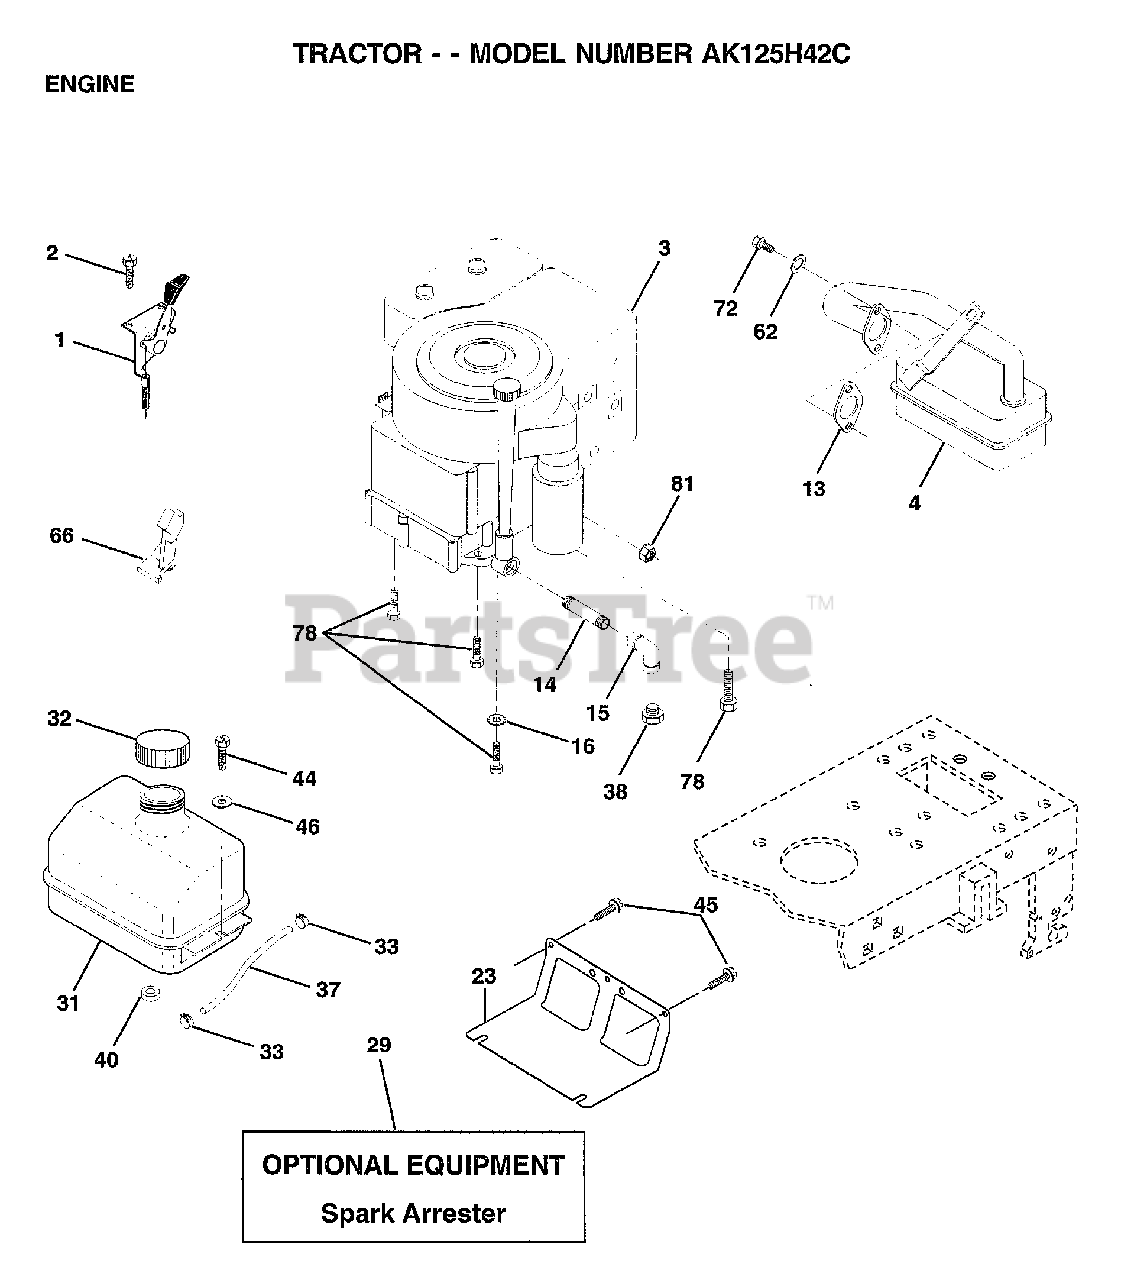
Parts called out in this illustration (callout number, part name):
1	CONTROL.THTL.23.5
2	SCREW LT
4	MUFFLER
14	PIPE NIPPLE
15	ELBOW
16	LOCKWASHER
23	SHIELD BROWNING
31	TANK.FUEL.LT.
32	CAP ASM FUEL
33	HOSE CLAMP
37	LINE FUEL
44	SCREW
45	SCREW
46	WASHER
62	LOCKWASHER
66	"STOP,DASH THROTT"
72	SCREW
78	SCREW
81	NUT
